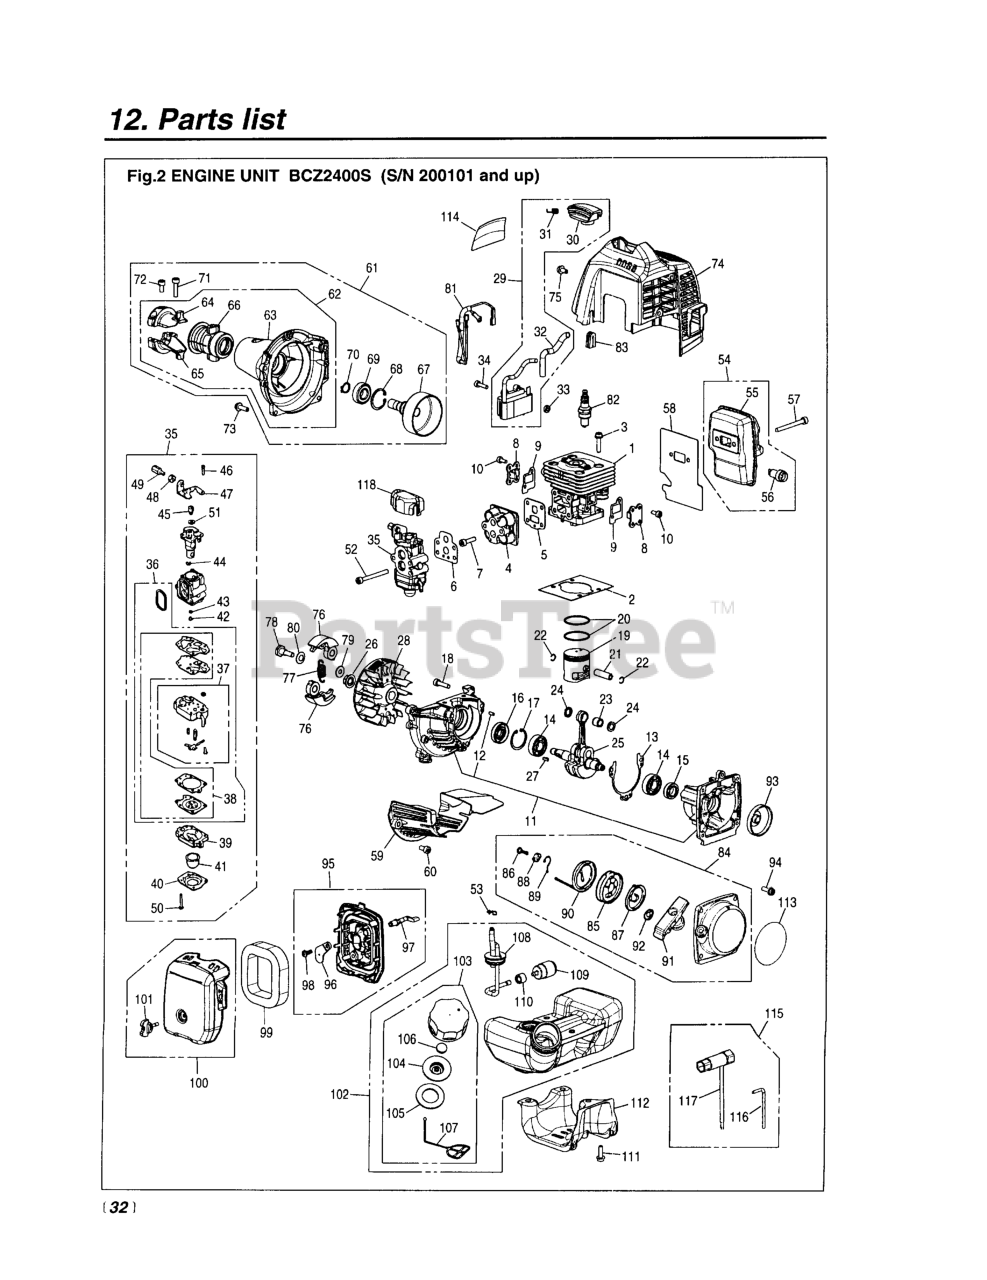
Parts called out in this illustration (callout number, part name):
1	CYLINDER
2	GASKET, BASE
3	BOLT
4	INSULATOR
5	GASKET, INSULATOR
6	GASKET, CARB.
7	BOLT, TORX
8	COVER, TR
9	GASKET, TR
10	BOLT, TORX
11	CRANKCASE-C
12	PIN
13	GASKET, CASE
14	BEARING
15	SEAL
16	SEAL, OIL (RPLS 1140-21220)
17	RING, SNAP, M28 x 1.2
18	BOLT (RPLS 2850-14220)
20	RING, PISTON
21	PIN, PISTON
22	RING, SNAP (RPLS 1101-41320)
23	BEARING
24	WASHER
25	CRANKSHAFT COMP.
27	KEY
28	ROTOR
29	COIL-A
30	CAP (RPLS 4810-72110)
31	SPRING
33	SPACER (RPLS -71260)
34	BOLT TORX
36	REBUILD KIT
37	BODY-A
38	KIT, GASKET (REPLACES-06020)
39	BODY, PURGE
40	COVER, PUMP
41	PUMP, PRIMING
42	JET
43	RING, O
44	RING
45	SWIVEL
46	SCREW
48	NUT, CABLE ADJUSTER
49	SCREW, CABLE ADJUSTER
50	SCREW
51	WASHER
52	BOLT
53	CLIP
54	MUFFLER ASSEMBLY
55	MUFFLER (REPLACES -15110)
56	ARRESTER
57	BOLT
58	GASKET, MUFFLER
59	PLATE
60	BOLT
62	HOUSING COMP (RPLS. -31110)
64	BRACKET (A) (RPLS -31211)
65	BRACKET (B)
66	CUSHION (RPLS -31231)
68	RING, SNAP, M28 x 1.2
70	RING, SNAP (RPLS 3130-13270)
71	BOLT (RPLS 2850-14220)
72	BOLT
73	BOLT
74	COVER, ENGINE
76	SHOE
77	SPRING
78	BOLT
79	WASHER, FLAT (USE 182303)
80	WASHER (RPLS -51241)
81	CORD COMP.
82	SPARK PLUG (CMR7H)
83	GROMMET
84	RECOIL-A
85	REEL
86	SCREW
87	SPRING, SPIRAL
88	COLLAR
89	ARM
90	ROPE (REPLACES 4500-75160)
91	KNOB (RPLS -75420)
92	PLATE, STOPPER
93	PULLEY
94	BOLT
96	PLATE, CHOKE
97	LEVER
98	SCREW
99	ELEMENT
101	KNOB
102	TANK-A
103	CAP ASSY (RPLS -85201)
104	HOLDER (REPLACES -85230)
105	PACKING
106	FILTER
107	STOPPER
109	FILTER ASSY
111	BOLT
112	GUARD, TANK
113	LABEL, RECOIL
114	LABEL, COVER
116	BAR
118	COVER
